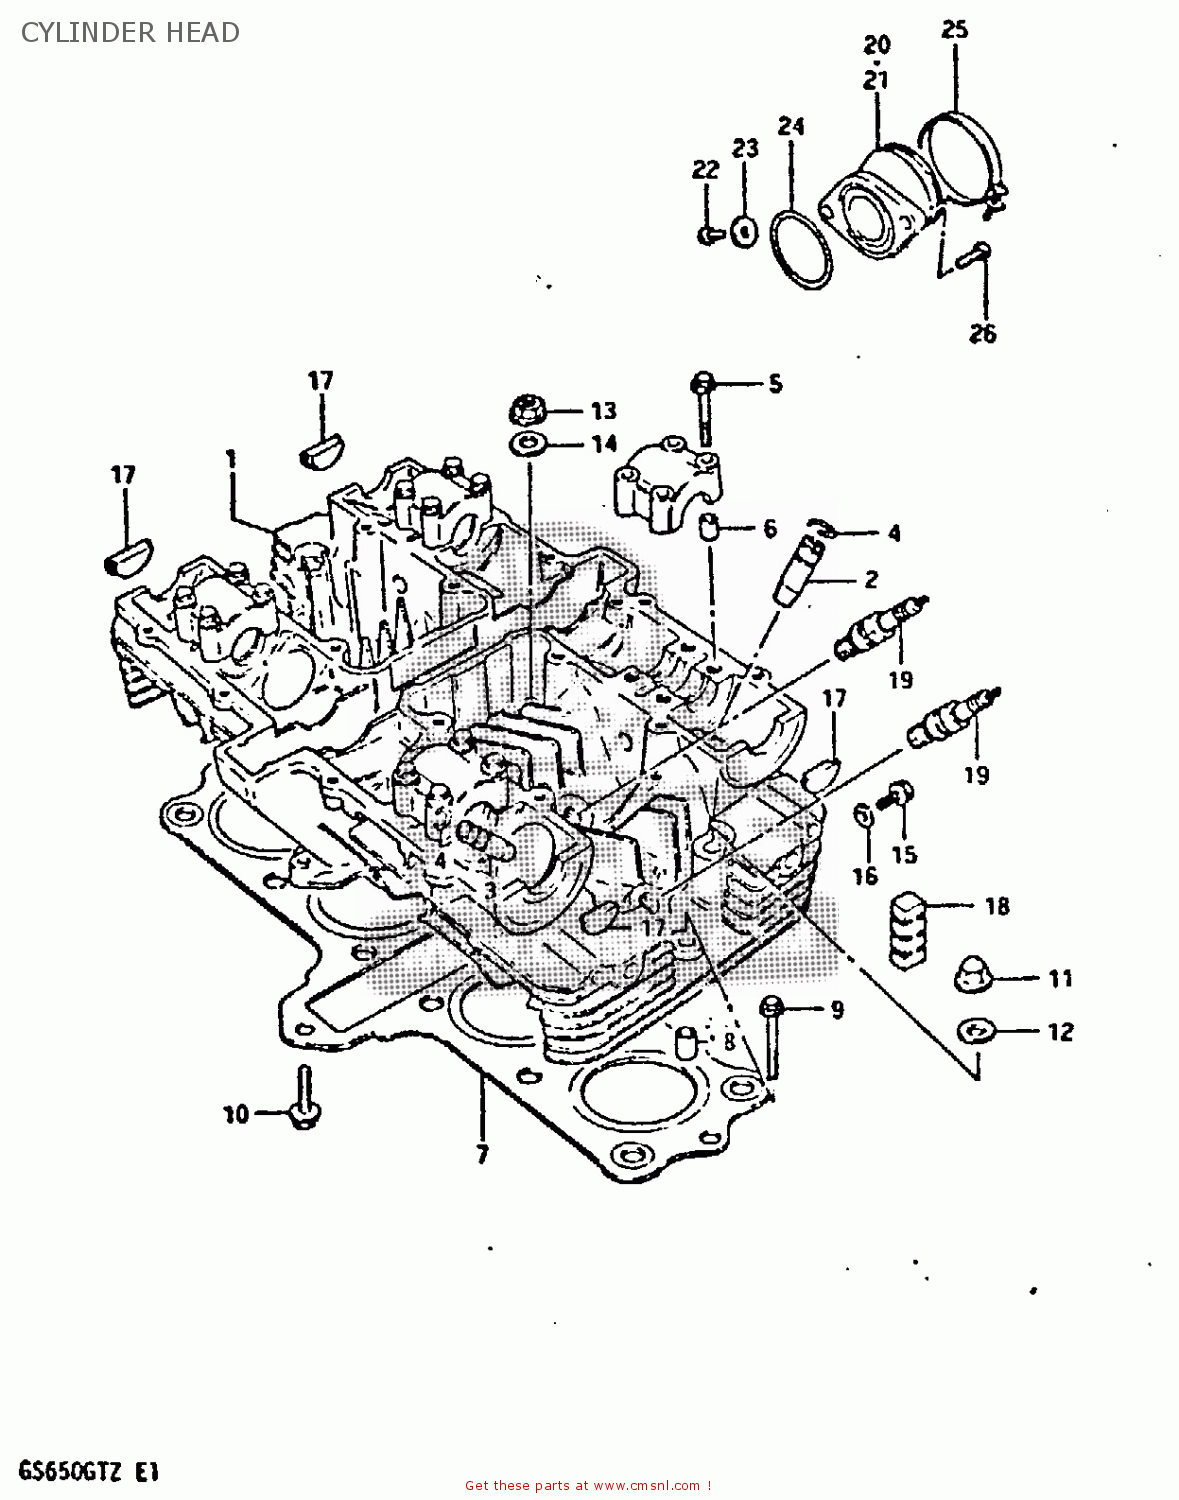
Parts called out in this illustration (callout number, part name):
1	HEAD,CYLINDER
2	GUIDE,INTAKE VALVE
3	GUIDE,EXHAUST VALVE
4	RING,SNAP
5	BOLT(6X39)
6	PIN(6.2X8X11)
7	GASKET,CYLINDER HEAD (MCA)
8	PIN
9	BOLT,UNDER
10	BOLT
11	NUT
12	GASKET(8.5X20X2.3) (NAS)
13	NUT
14	WASHER(8.5X19X2.3)
15	BOLT
16	GASKET (NAS)
17	PLUG
18	PAD,CYLINDER
19	SPARK PLUG DR8ES-L
20	PIPE,INTAKE,R
21	PIPE,INTAKE,L
22	BOLT
23	WASHER
24	O-RING
25	CLAMP
26	SCREW
